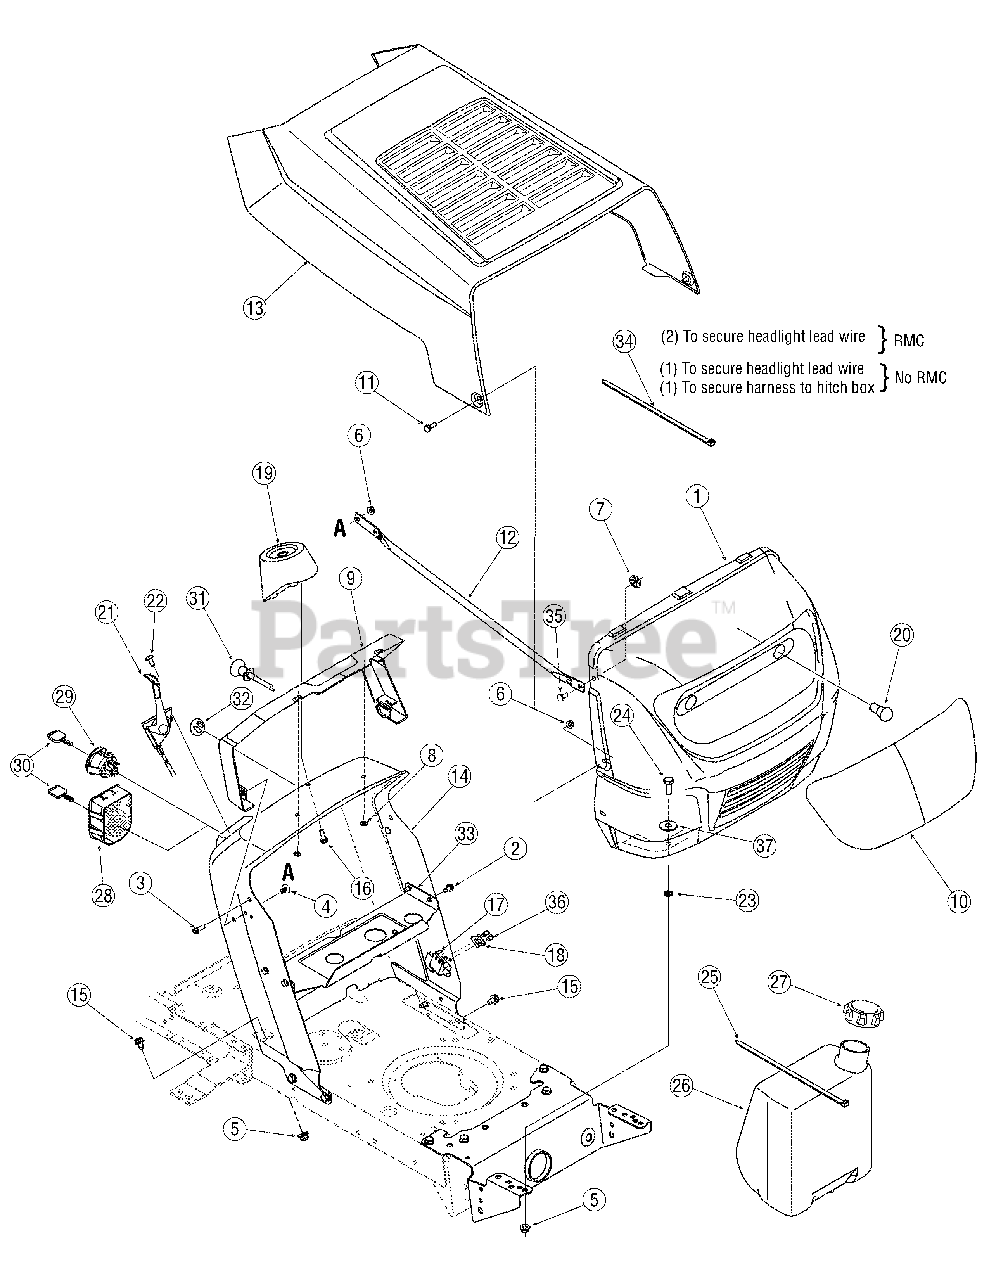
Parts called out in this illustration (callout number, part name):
2	Screw, 1/4-20, 0.500
3	Screw, 1/4-20, 0.750
4	Ratchet Clip .250 dia. x .500 lg.
5	Nut, Flange Lock, 5/16-18, GrF
6	Nut, Flange Lock, 1/4-20, GrF
7	Nut, Push-on, .25 Dia
8	Push Nut, .25ID x .50OD
9	Collar, Dash, 0-Style
10	Lens
11	Screw, Shldr, .375 x .125, 1/4-20
15	Screw, 5/16-18, 0.625
16	Screw, 1/4-15, 0.750
17	Switch
18	Switch Plate
19	Support, Steering
20	Headlamp, 12V
21	Throttle/Choke Cable, 25" (Sgl. Cyl.)
21	Throttle Control, 39" (Twin Cylinder)
22	SCREW 1/4-20 x .500
23	Speed Nut, .3125
24	SCREW 5/16-18 x .75 GR5
25	Cable Tie, 34.75
26	Fuel Tank, 1.5 gal.
27	Fuel Tank Cap
28	Module, Ignition Switch (RMC)
29	Module, Ignition Switch (No RMC)
30	Key
31	Choke Control, 37.5"
32	Choke Plug
34	Cable Tie
35	Rivet, Flat Head 1/4"
36	Pop Rivet
37	Flat Washer, .344 x 1.00 x .063
